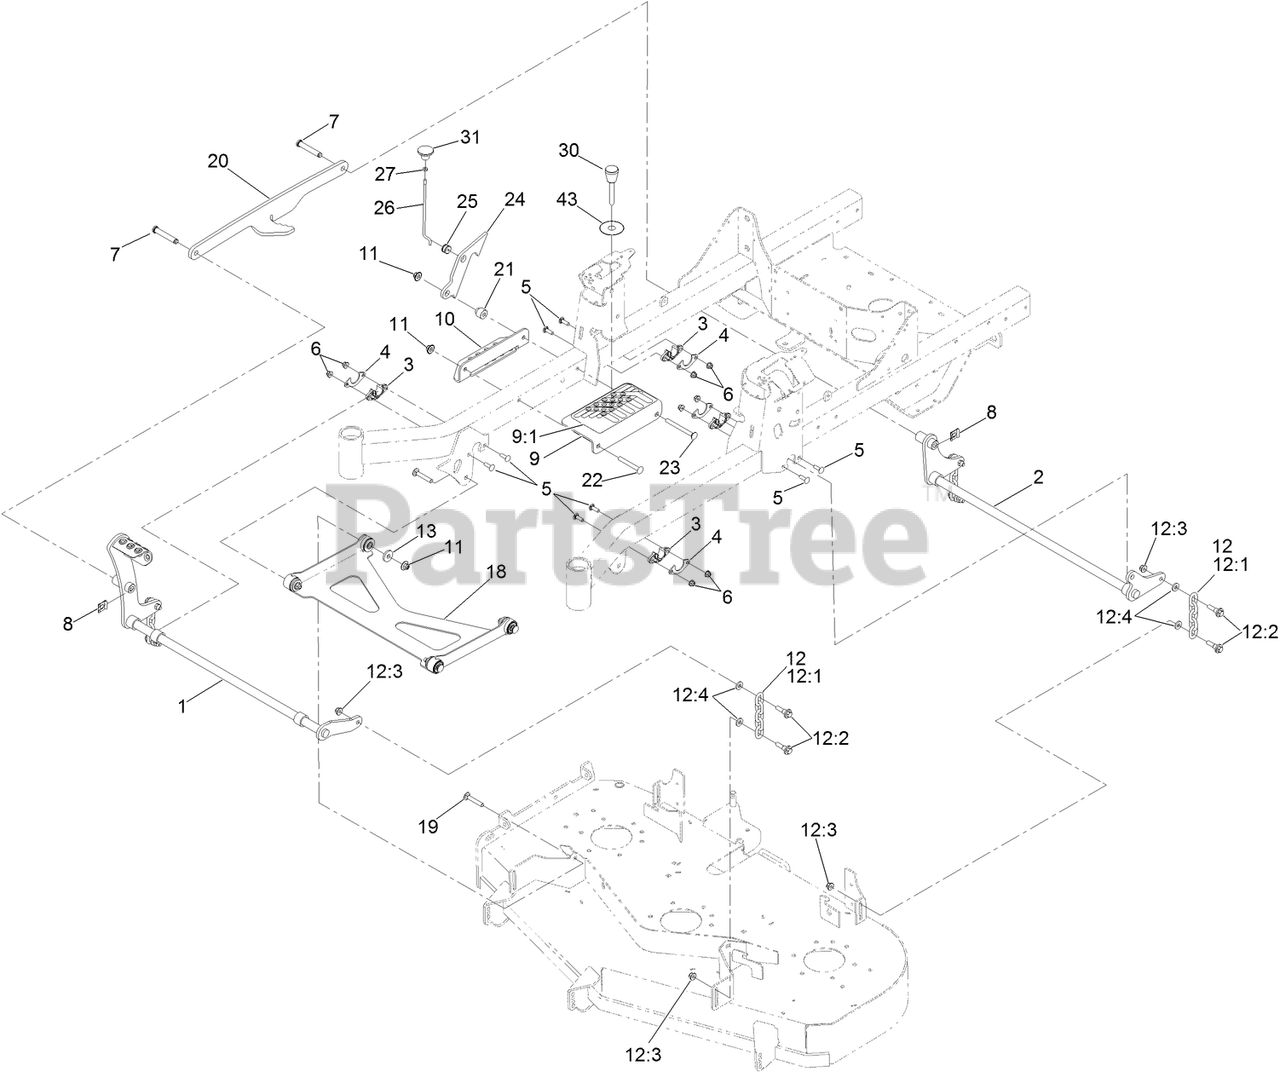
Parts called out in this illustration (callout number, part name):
1	SHAFT-LIFT, DECK
2	SHAFT-LIFT, DECK (REAR)
3	BUSHING-FLANGE
4	GUSSET-LIFT, DECK
5	SCREW-CARR
6	NUT-HF, NI
7	PIN-CLEVIS
8	CLIP-PIN
9	BRACKET ASM
9:1	DECAL-HOC
10	ANGLE-HOC, LOWER
11	NUT-FLANGE, NI
12	DECK CHAIN ASM
12:1	CHAIN-LIFT, DECK
12:2	BOLT-SHOULDER
12:3	NUT-HF, NI
12:4	SPACER
13	WASHER
18	DECK STRUT ASM
19	SCREW-CARR
20	LINK-LIFT
21	SPACER-STEPPED
22	SCREW-CARR
23	SCREW-CARR
24	PLATE-LOCK, TRANSPORT
25	GROMMET
26	ROD-LOCK, TRANSPORT
27	NUT-JAM
30	PIN-HOC
43	TAG-RETENTION, MAGNETIC
